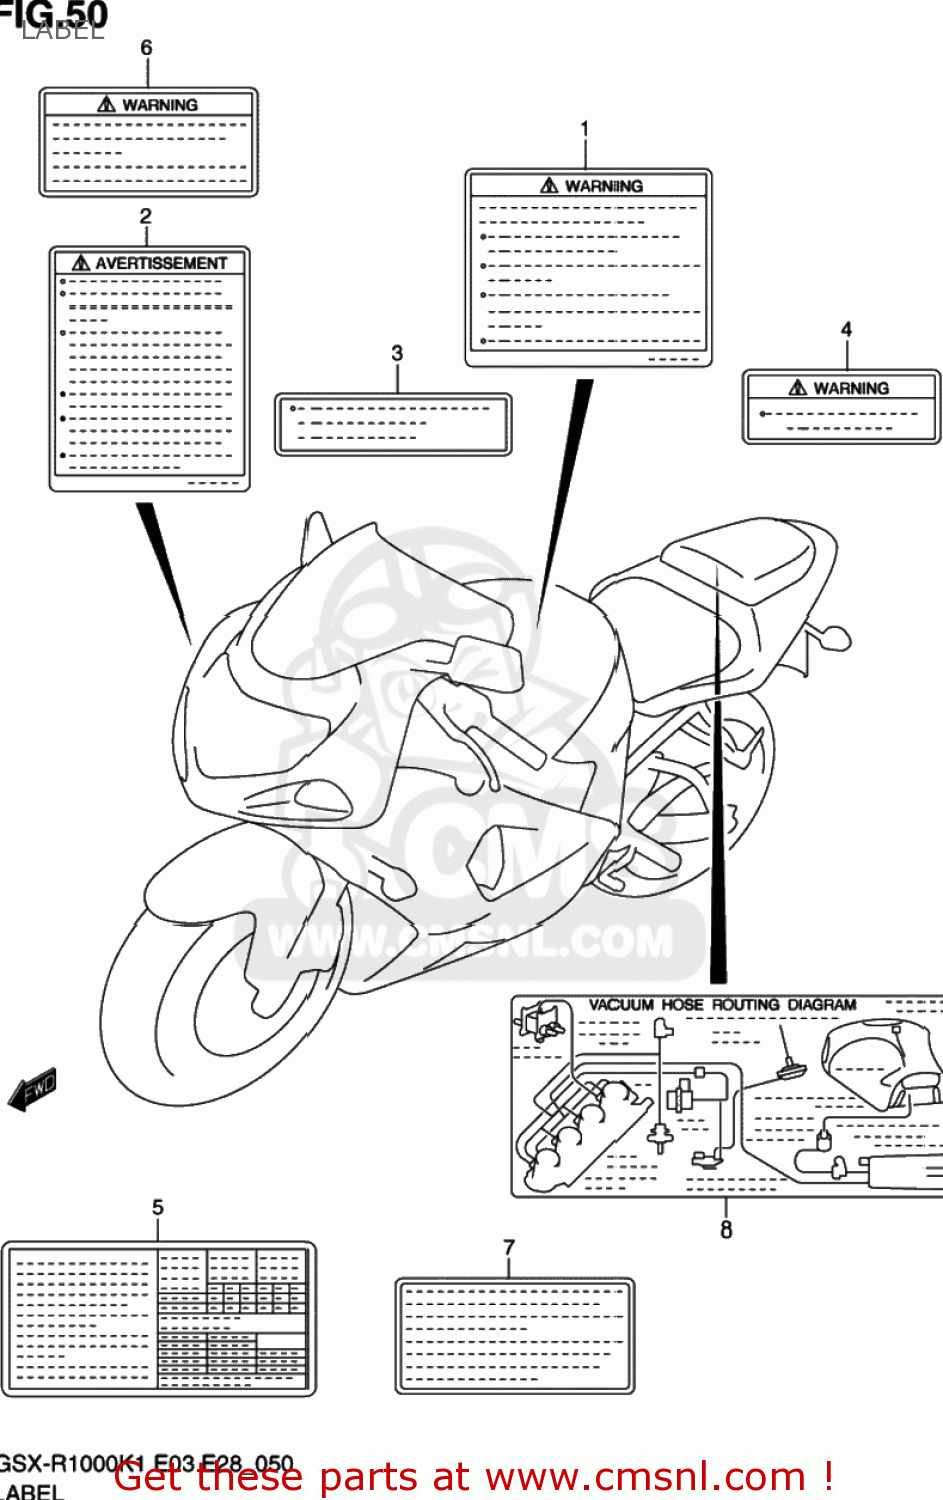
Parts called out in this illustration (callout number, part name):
1	LABEL,GENERAL WARNING
2	LABEL,SCREEN
3	LABEL,FUEL INFORMATION
4	LABEL,LOADING CAPACITY
5	LABEL
6	LABEL,WARNING STEERING
7	LABEL,MANUAL NOTICE
8	LABEL,VACUUM HOSE ROUTING
9	MANUAL,OWNER'S
